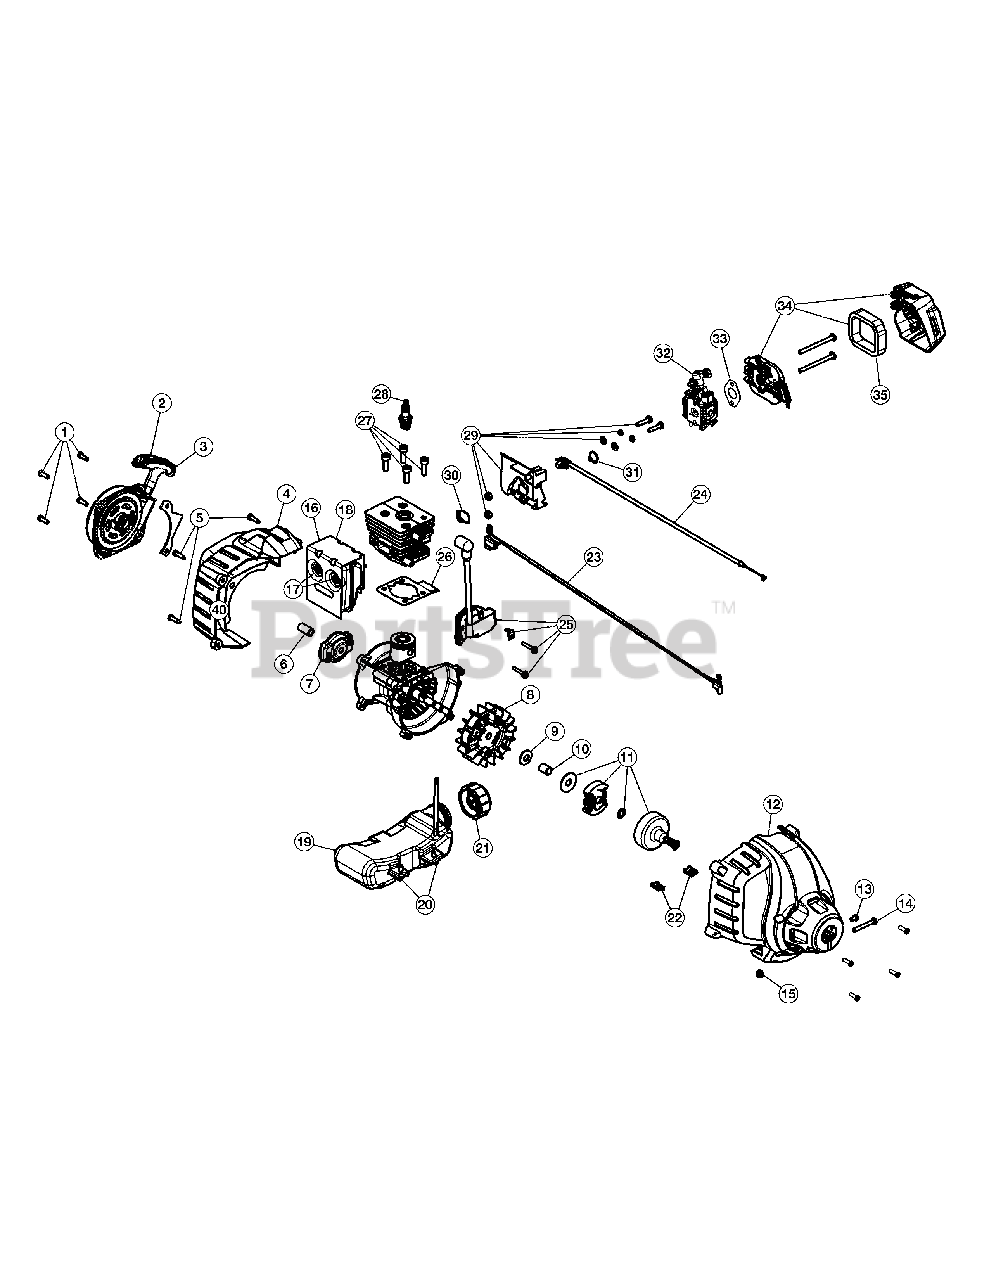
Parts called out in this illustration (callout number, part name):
1	Starter Assembly (Incl. 2 & 3)
2	Starter Screw
3	Starter Assembly Guard (Incl. 2)
4	Rear Engine Cover (Incl. 5)
5	Cover Screw
6	Adapter
7	Pawl Assembly
8	Flywheel Assembly
9	Washer
10	Spacer
11	Clutch Assembly
12	Clutch Cover Assembly (Incl. 2, 13 -15 and 22)
13	Anti-Rotation Screw
14	Clamp Screw
15	Clamp Nut
16	Muffler Assembly (Incl. 17 and 18)
17	Muffler Screw
18	Muffler Gasket
19	Fuel Tank Assembly (Incl. 20 and 21)
20	Tank Screw
21	Fuel Cap
22	U-shaped Nut
23	Lead Wires
24	Throttle Cable
25	Module Assembly
26	Cylinder Gasket
27	Cylinder Bolt
28	Spark Plug
29	Insulator Assembly (Incl. 30 and 31)
30	Insulator O-Ring
31	Carburetor O-Ring
32	Carburetor
33	Carburetor Gasket
34	Air Cleaner Assembly (Incl. 35)
35	Air Cleaner Filter
